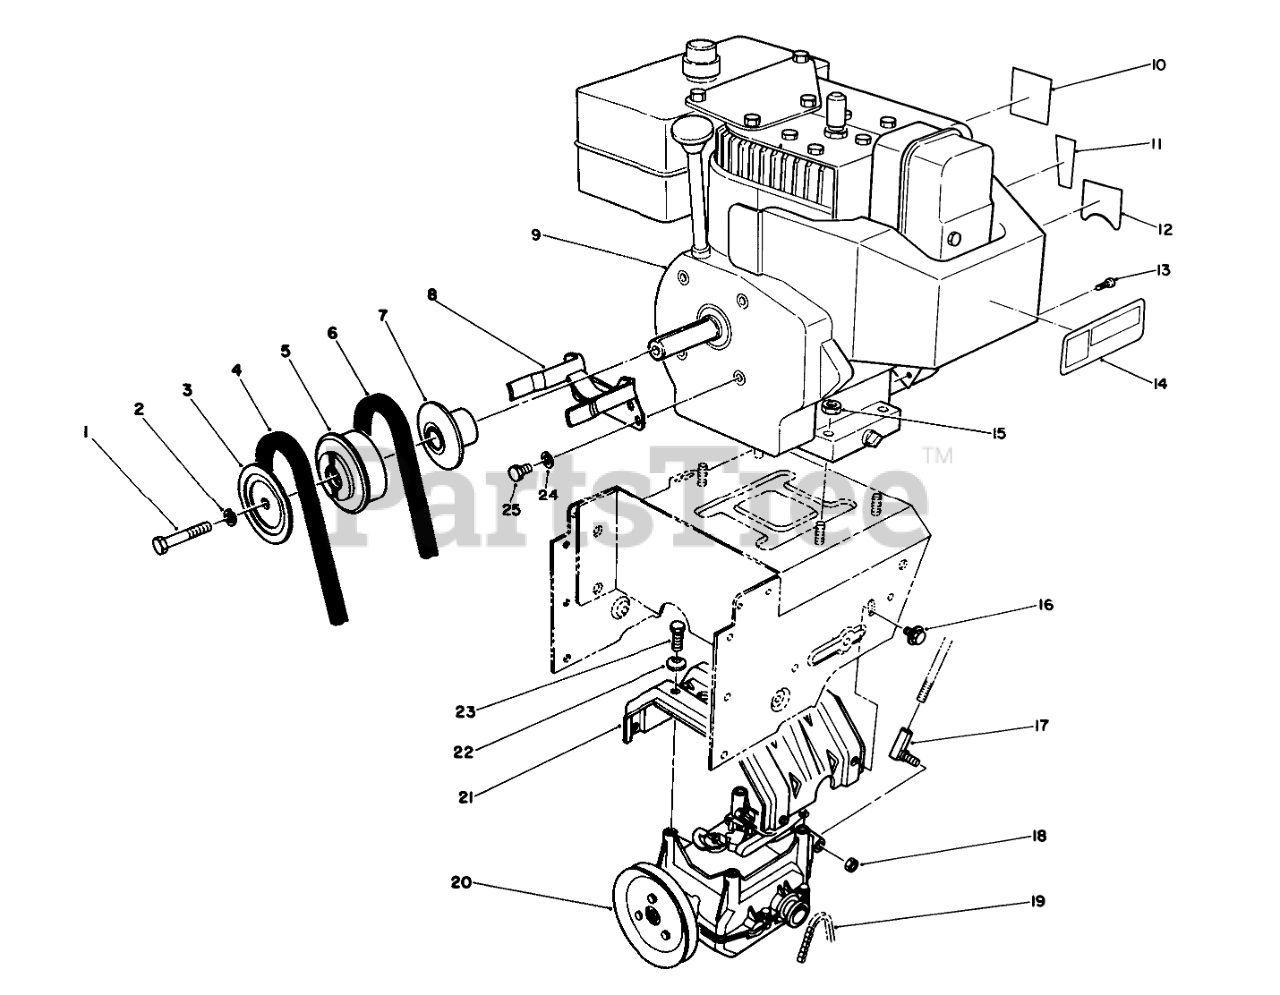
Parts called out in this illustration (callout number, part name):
1	SCREW-HH
2	WASHER-LOCK
3	Sheave Half-Impeller
4	V-BELT
5	LH CASTOR ARM ASM
6	V-BELT-TRACTION
7	TENSION BUSHING
8	Guide-Belt
10	DECAL-PRIMER
11	DECAL-THROTTLE
12	DECAL-CHOKE
13	SCREW-HWH
14	DECAL-WARNING, HOT SURFACE
15	NUT-HF
16	SCREW-HHF
17	JOINT-BALL
18	NUT-LOCK, NI
19	CHAIN
20	TRACTION GEARCASE ASM
21	Frame-Transmission
22	WASHER-SPRING
23	SCREW-HWHTF
24	WASHER-LOCK
25	SCREW-HH
